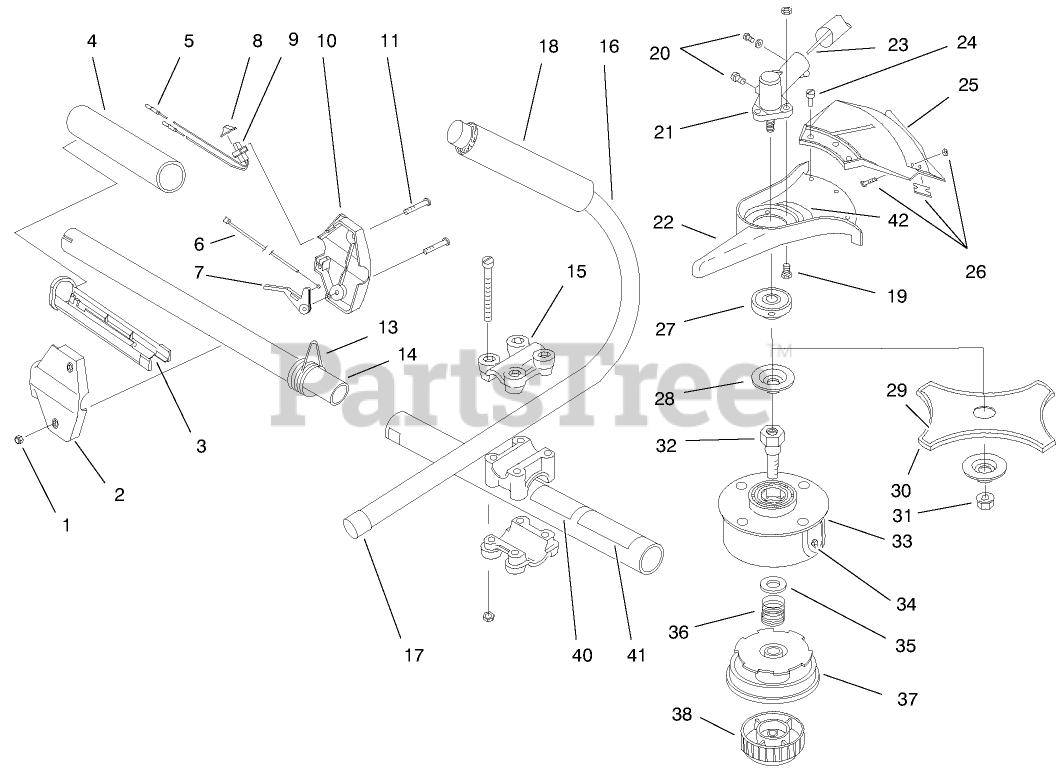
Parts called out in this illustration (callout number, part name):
1	NUT-LOCK, NI
2	RH HOUSING
3	TROUGH 1"
4	GRIP - RUBBER
5	LEAD WIRE ASM
8	SWITCH COVER
9	SWITCH
10	LH HOUSING
15	HANDLE BRACKET ASM
16	ASSEMBLY - J-HANDLE
17	TUBE CLOSURE
18	HANDLE NITRILE GRIP
20	MTG HDW&PLUG SET
23	FLEXIBLE DRIVE SHAFT
24	GUARD MNTG SCREW ASM
25	GUARD & BLADE ASM
26	BLADE ASM
29	BLADE SAFETY GUARD
31	BLADE RETAINER NUT
34	EYELET
35	RETAINER
36	SPRING
41	DECAL - SAFETY
42	DECAL - WARNING
